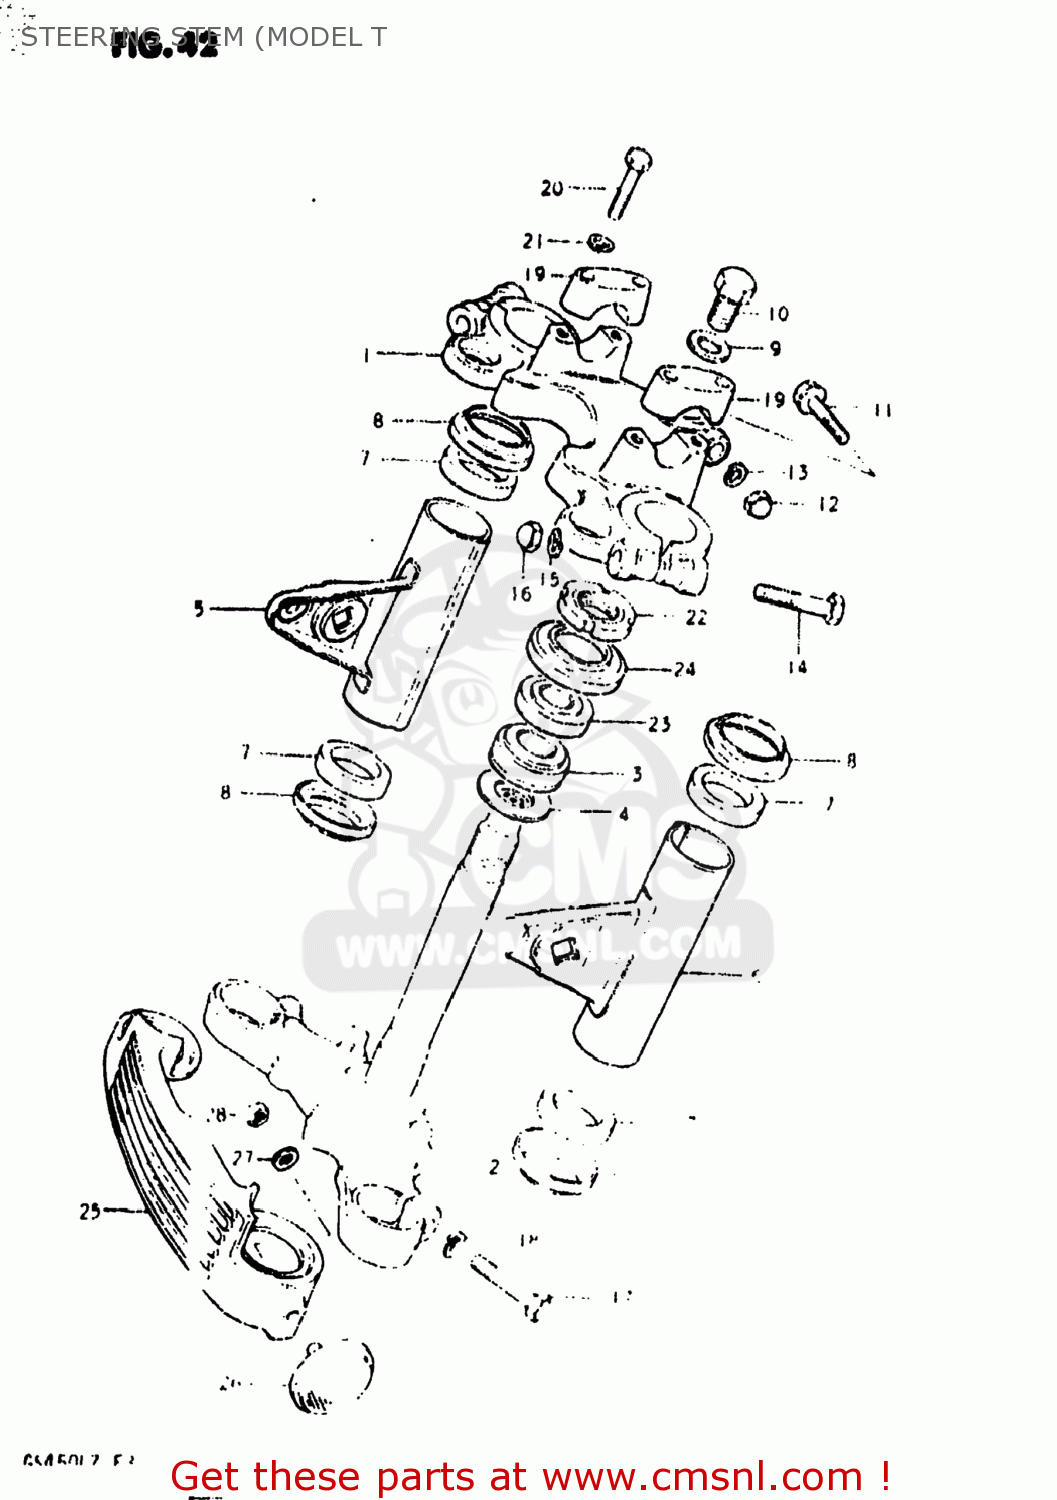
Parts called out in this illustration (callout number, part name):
1	HEAD,STEERING STEM
2	STEM,STEERING
3	BEARING
4	WASHER,THRUST
5	BRACKET,HEADLAMP,RIGHT
6	BRACKET,HEADLAMP,LEFT
7	CUSHION,HEADLAMP BRACKET
8	CAP,HEADLAMP BRACKET
9	WASHER
10	BOLT(12X20)
11	BOLT
12	NUT,M8X1.25X12
13	LOCK WASHER
14	BOLT 10X55
15	LOCK WASHER
16	NUT 10MM
17	BOLT 10X40
18	LOCK WASHER
19	HOLDER,HANDLE UPR
20	BOLT
21	LOCK WASHER
22	NUT,STEERING STEM(25X44X10)
23	TAPER,ROLLER BEARING
24	DUST SEAL,STEERING,UPPER
25	COVER,FRONT FORK
26	REFLEX REFLECTOR,RR
27	WASHER
28	NUT
